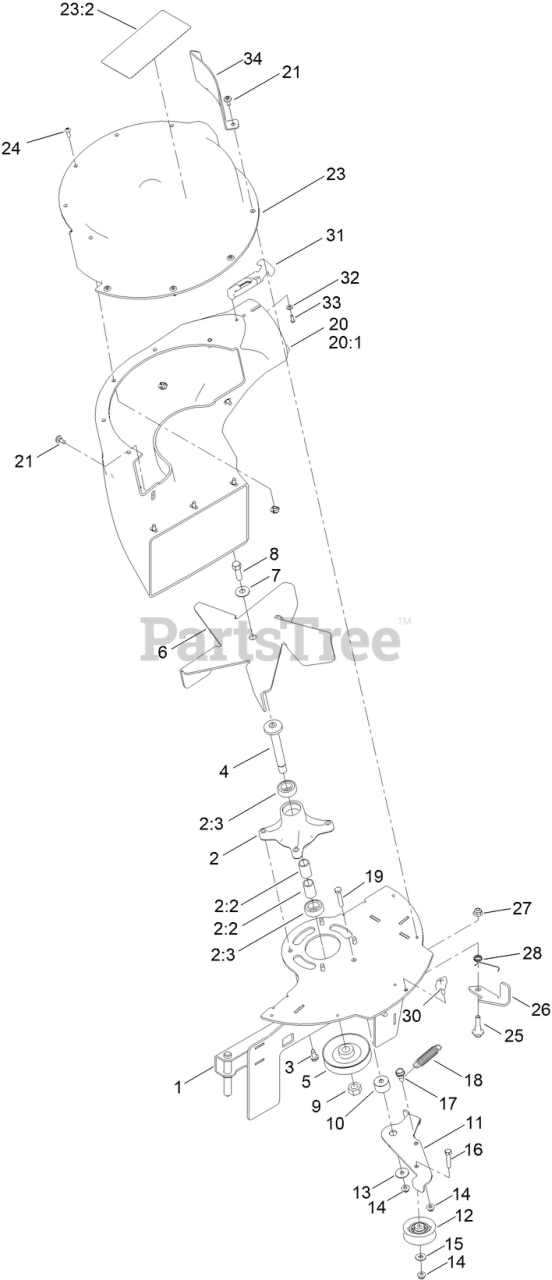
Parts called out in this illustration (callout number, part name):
1	FRAME-BLOWER
2	SPINDLE ASM
2:2	SPACER
2:3	BEARING-BALL
3	SCREW-HWHTF
4	SHAFT - SPINDLE
5	PULLEY-BLOWER
6	FAN-BLOWER
7	WASHER-BELLEVILLE
8	SCREW-HH
9	NUT-HEX
10	SPACER-IDLER ARM
11	IDLER ARM, BLOWER
12	PULLEY-IDLER, FLAT
13	WASHER-PIVOT
14	NUT-HF
15	WASHER-FLAT
16	SCREW-HH
17	BOLT SHOULDER
18	SPRING-PEDAL, RETURN
19	SCREW-HH
20	BLOWER CHUTE ASM
20:1	CHUTE-BLOWER
21	SCREW-SHOULDER
23	BLOWER COVER ASM
23:2	DECAL-DANGER
24	SCREW-PRH
25	BOLT-SHOULDER
26	LATCH-BLOWER
27	NUT-HF, NI
28	SPRING-TORSION
31	LATCH-RUBBER
32	WASHER-PLAIN
33	SCREW-HSBH
34	GUARD-BLOWER
